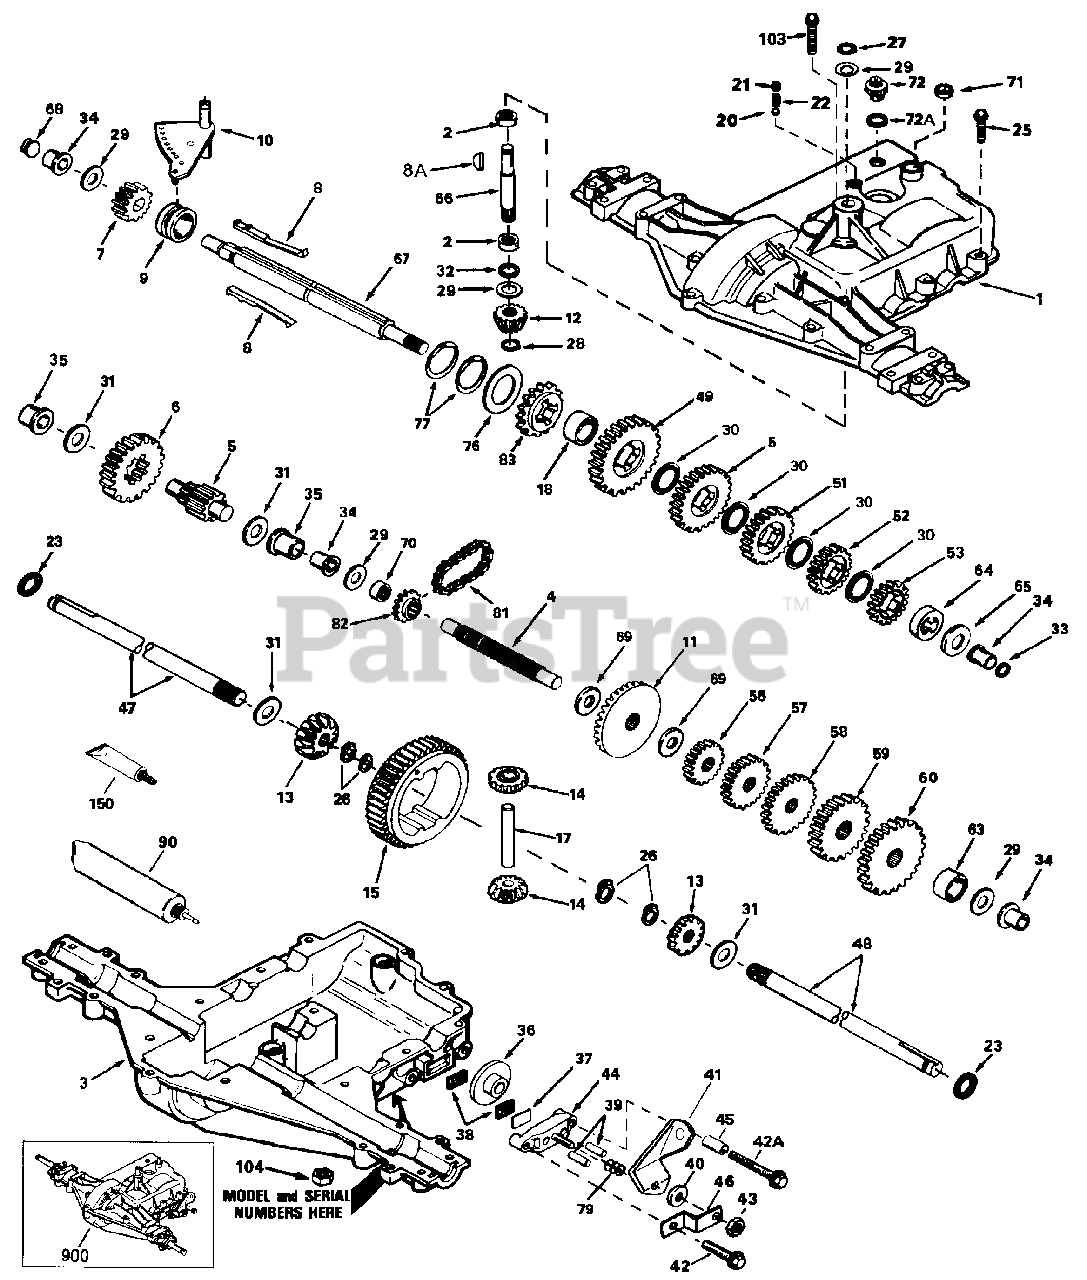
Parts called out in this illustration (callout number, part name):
1	Cover, Transaxle
2	Bearing, Needle
3	Case, Transaxle
4	Shaft, Counter
5	Shaft and Pinion Assembly, Output
6	Gear, Output
7	Gear, Spur, 15 Teeth
8	Key, Shift
8A	Key, Woodruff
9	Collar, Shifter
10	Rod and Fork Assembly, Shift
11	Gear, Bevel, 42 Teeth
12	Bevel Pinion, Input
13	Gear, Bevel
14	Gear, Bevel Pinion
15	Gear, Ring
17	Pin, Drive
18	Spacer, Neutral
20	Ball, Steel 5/16" diameter
21	Set Screw 3/8-16 x 3/8
23	Ring, Seal
25	Screw, Flanged Hex Head, Thread Forming 1/4-20 x 1-1/4
26	Ring, Retainer
27	Ring, Retainer
28	Ring, Retainer
29	Washer, Thrust
30	Washer, Thrust
32	'O' Ring
33	Seal, Square Cut
34	Bushing, Flanged
35	Bushing, Flanged
36	Disk, Brake
37	Plate, Brake Pad
38	Pad, Brake
39	Pin, Dowel
40	Washer, Flat
41	Lever, Brake
42	Screw, Flanged Hex Head, Thread Forming 1/4-20 x 1-1/4
42A	Screw 1/4-20 x 2-1/4
43	Locknut 5/16-24
44	Holder, Brake Pad
46	Bracket, Brake Lever
47	Axle
48	Axle
49	Gear, Spur, 37 Teeth, Steel (1st)
50	Gear, Spur, 30 Teeth (2nd)
51	Gear, Spur, 25 Teeth (3rd)
52	Gear, Spur, 22 Teeth (4th)
53	Gear, Spur, 19 Teeth, Steel (5th)
56	Gear, Spur, 12 Teeth (1st)
57	Gear, Spur, 20 Teeth (2nd)
58	Gear, Spur, 25 Teeth (3rd)
59	Gear, Spur, 28 Teeth (4th)
60	Gear, Spur, 31 Teeth (5th)
65	Washer, Thrust
66	Shaft, Input
67	Shaft, Brake, 4 Keyed
69	Washer, Thrust
71	Seal, Square Cut
72	Plug, Threaded 9/16-18
72A	'O' Ring
76	Washer, Thrust
77	Ring, Retaining, Inverted
79	Spring, Brake
81	Chain, Roller
82	Sprocket, 9 Teeth (Reverse)
83	Sprocket, 18 Teeth (Reverse)
90	Grease, Bentonite, 32 Ounce Bottle
103	Screw 1/4-20 x 2
104	Locknut 1/4-20
150	Gasket Eliminator (Loctite #515)
